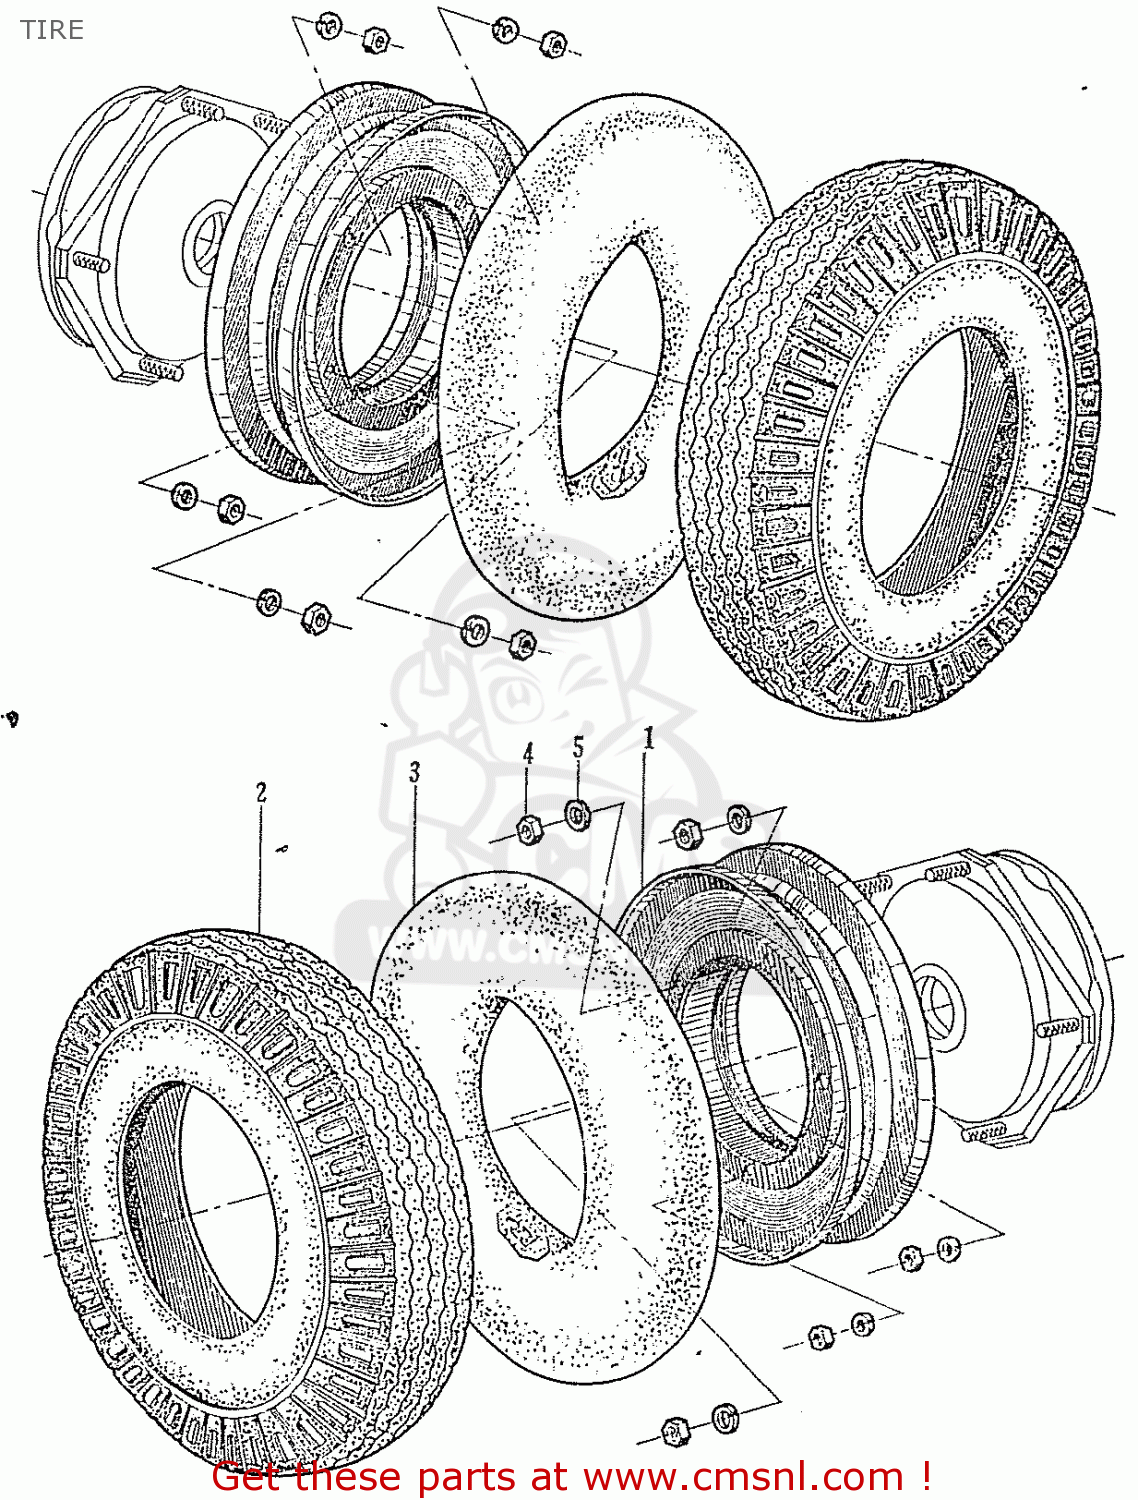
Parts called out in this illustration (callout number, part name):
1	WHEEL
2	TIRE, SPARE
3	TUBE
4	NUT, WHEEL
5	SPG-WASHER 10MM
